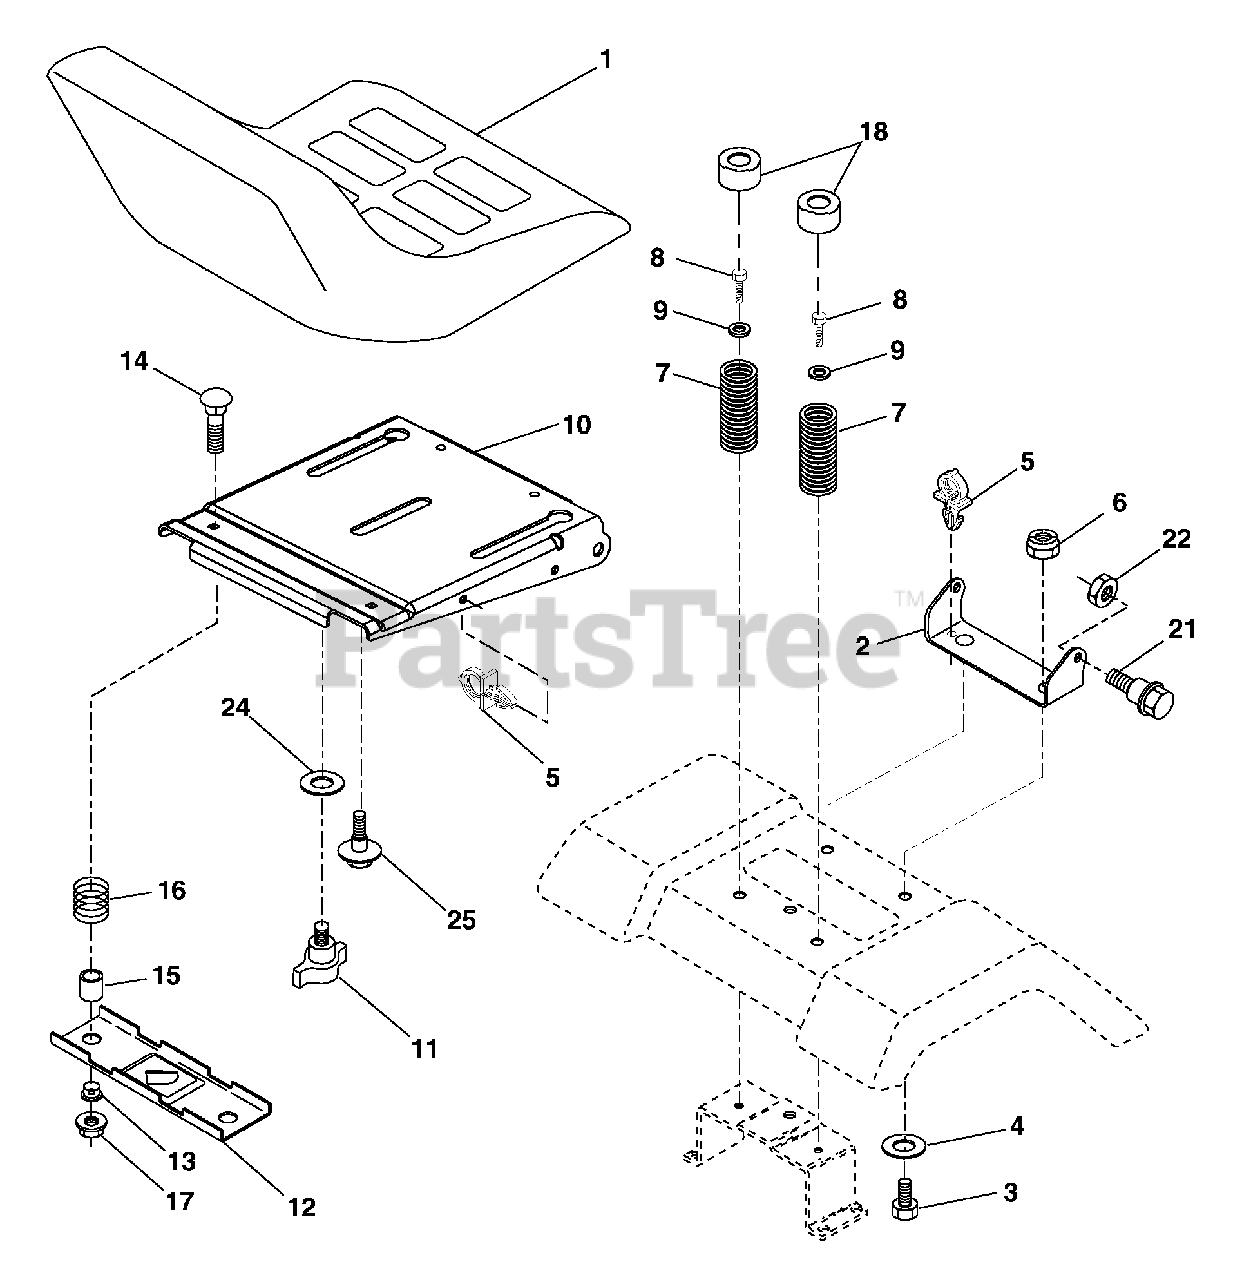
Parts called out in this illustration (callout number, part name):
1	Seat
2	Bracket Pivot Fender
3	Bolt Fin Hex 3/8-16 unc x 1
4	Washer 13/32 x 1 x 10 Ga.
5	Clip Push-In
6	Nut Hex w/Ins. 3/8-16 unc
7	Spring Seat Cprsn 2 250 Blk Zi
8	Screw 3/8-16 x 1.5 Smgml
9	Washer 13/32 x 1 x 14 Ga.
10	Pan Seat
11	Knob Seat
12	Bracket Mounting Switch
13	Bushing Snap Blk Nyl 50 Id
14	Bolt Rdhd Sqnk 1/4-20 x 1-1/2
15	Spacer Split 28x 88
16	Spring Cprsn
17	Nut Lock 1/4 Lge Flg Gr. 5 Zinc
18	Cap Spring
21	Bolt Shoulder 5/16-18 unc
22	Nut Hex Lock W/Ins 5/16-18
24	Washer 17/32 x 1-3/16 x 12 Ga.
25	Bolt Shoulder 5/16-18 x 62
